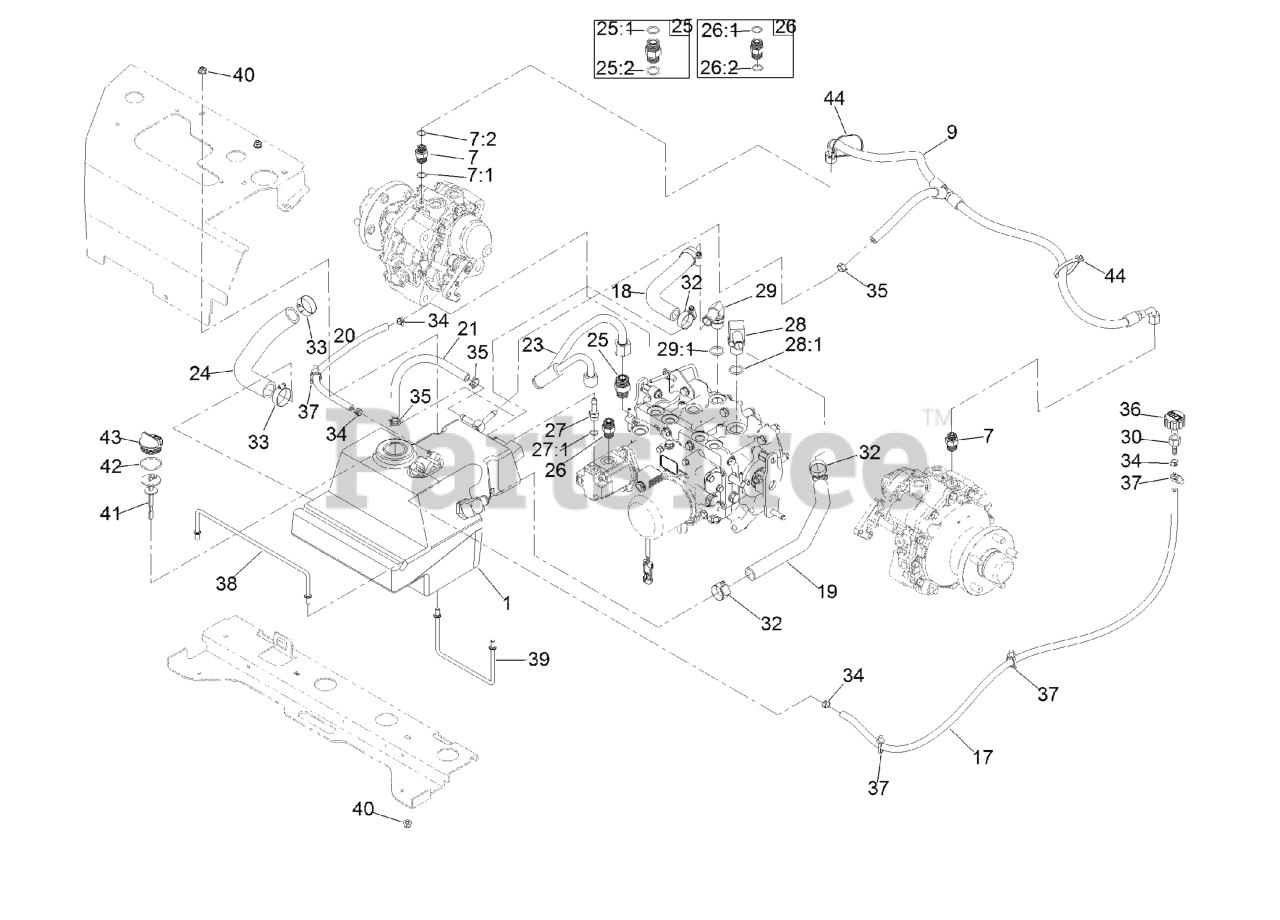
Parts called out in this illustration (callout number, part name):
1	HYD RESERVOIR ASM
7	FITTING-STRAIGHT
7:1	O-RING
7:2	O-RING
9	TEE HOSE ASM
18	HOSE-RETURN
19	HOSE-RETURN
23	TUBE ASM
24	HOSE-SUCTION
25	FITTING-STRAIGHT
25:1	O-RING
25:2	O-RING
26	FITTING-STRAIGHT
26:1	O-RING
26:2	O-RING
27	ADAPTER-STRAIGHT
27:1	O-RING
28	FITTING-ELBOW, 90
28:1	O-RING
29	FITTING-90
29:1	O-RING
30	FITTING-STRAIGHT
32	CLAMP-HOSE
33	CLAMP-HOSE
34	CLAMP-HOSE
35	CLAMP-HOSE
36	BREATHER
37	CLIP-TIE
38	ROD-SUPPORT, HYD TANK
39	ROD-SUPPORT, HYD TANK
40	NUT-HF, NI
41	DIPSTICK
43	PLUG-PLASTIC
44	TIE-PLASTIC
